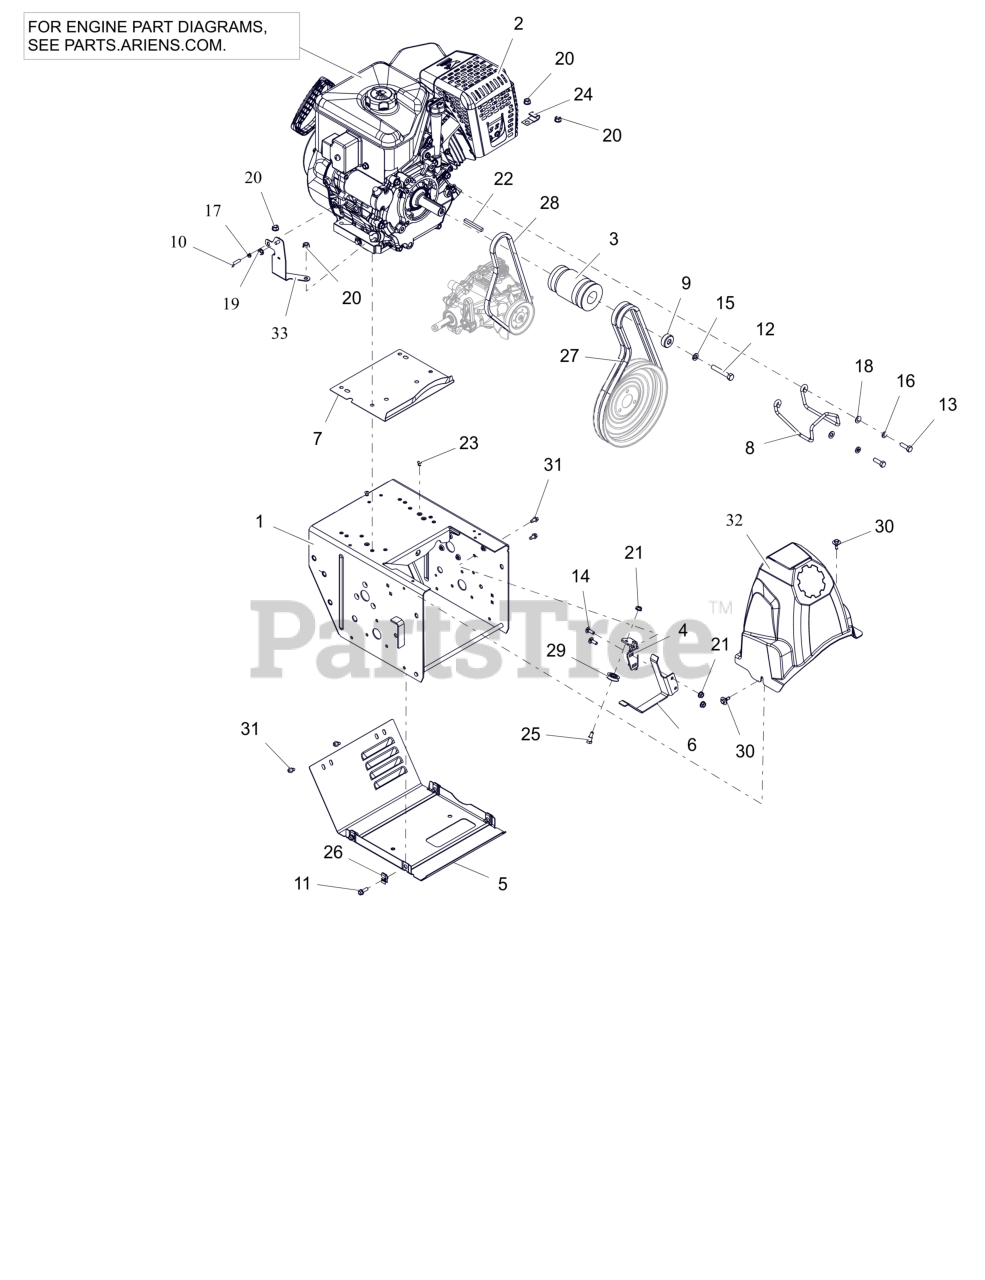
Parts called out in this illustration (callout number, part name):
1	FRAME, MAIN - PRO (WELDMENT)
2	ENGINE, EFI 420 GEN 3 240V/60W
3	SHEAVE, COMBO HYDRO WHEEL 4L
4	BRACKET, CLUTCH CABLE
5	COVER, BOTTOM - VENTILATED
6	FINGER, BELT - FLAT
7	BAFFLE, WATER - LARGE BLOCK
8	FINGER, BELT
9	BSHG, SPCR .406 X 1.250 X .500
10	BLT,HEX M6-1X25 G8.8 ZC120
11	BLT, HWH .25-20X.75 G5 ZCC
12	BLT, HEX .38-24X2.25 G5 ZCC
13	BLT, HEX 0.3125-24X1 G5 ZCC
14	BLT, RHSN .25-20X.750 G5 ZCC
15	WSHR,LK-REG .375X.094 ZCC
16	WSHR, LK-HVY .312X.097 ZCC
17	WSHR,LK-REG .250X.062 ZCC
18	WSHR,FLT .344X.688X.065 ZCC
19	NUT-LK-CTR-FLG .25-20 ZC120
20	NUT,LK-CTR-FLG .31-18 GF ZCC
21	NUT-LK-TOP-FLG .250-20 GF ZCC
22	KEY .25X.25X2.25
23	RVT, POP .1875 ZCC
24	J-CLAMP
25	BOLT, SHLDR -.375 X .375 X .25-20
26	NUT-RTNR .25-20X.56
27	V-BELT, HA-RAW EDGE (SET)
28	V-BELT, 4L-WRAPPED
29	PULLEY, CABLE
30	SCR-TAP .25-20X.5 CAPTIVE
31	SCR-TAP .25-20X.50 HWH ZCC
32	COVER, BELT
33	WLDMT- LG BLOCK FUSE MOUNT
